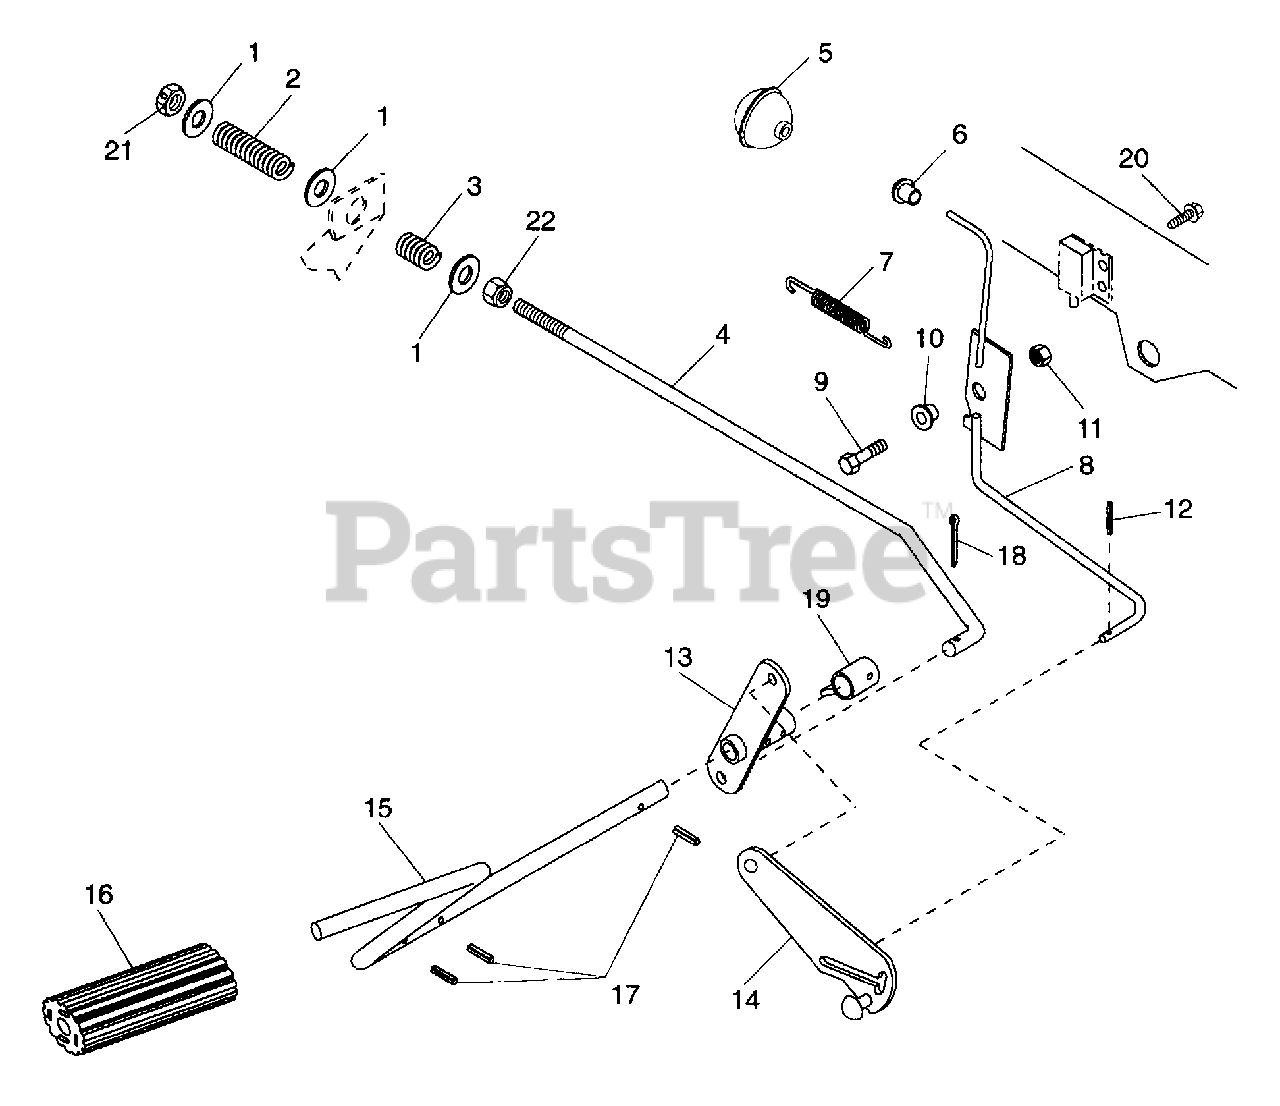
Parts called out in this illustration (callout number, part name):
1	WSHR-FL-STL.406X.812X.065PL
2	SG-COMP .048X.59X2.06 WLD9
3	SG-COMP .125X.78X1.00 YWZ
4	BRAKE ROD- HYDRO
5	PUSH/PULL CONTROL KNOB
6	SNAP BUSHING-.437
7	SG-TENS .051X.44X4.38 WLD 7.5
8	LEVER, PARKING BRAKE
9	BLT-HEX .31-18X.75 PL GR5
10	BSHG, FLG .325X.499X.26X.88
11	NUT-LK .312-18 GR A PL
12	PIN-ROLL .093X.50
13	ARM & HUB - HYDRO
14	PLATE, PIVOT
16	COVER- PEDAL
17	PIN-GRV .188X1.25 TP A
18	PIN-COTR .09X.75 PL
19	LEVER - BRAKE SWITCH
20	SCR-TAP 12-24X.50 HWH PL TR
21	NUT-LK-JAM-CTR .375-16 PL
22	NUT-LK-NYL .375-16 PL
